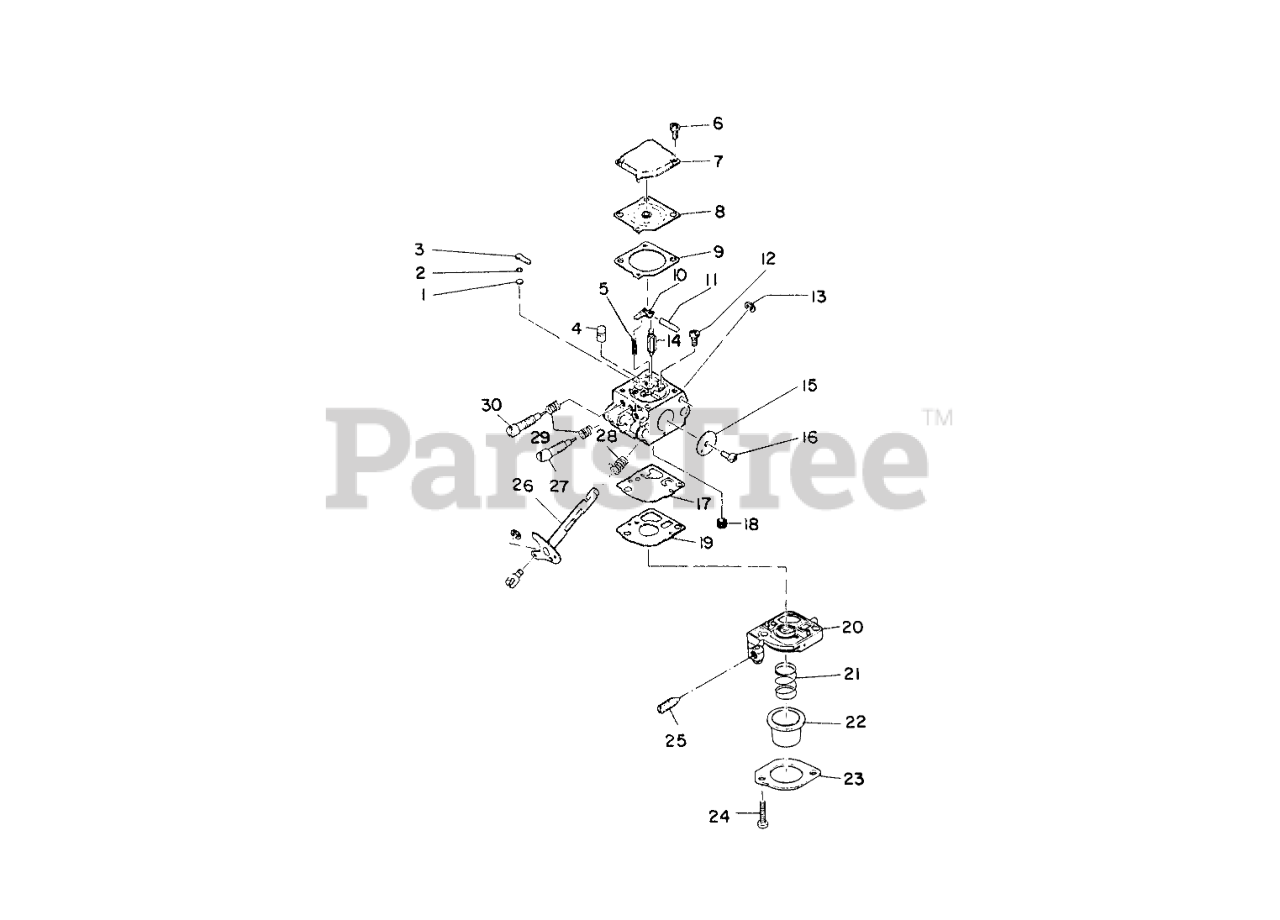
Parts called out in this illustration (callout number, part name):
1	Valve Check
2	Retainer-Check Valve
3	Plug-Welch
4	Nozzle Ass-y-Check Valve
5	Spring
6	Screw
7	Cover
8	Diaphram-Metering
9	Gasket
10	Lever-Metering
11	Pin-Metering
12	Screw
13	Ring-E
14	Valve-Inlet Needle
15	Valve-Throttle
16	Screw
17	Diaphram-Pump
18	Strainer
19	Gasket
20	Base Assembly-Primer (Incl. Ref. #25)
21	Spring
22	PRIMER
23	Retainer-Primer
24	Screw
25	Screw-Idle Adjustment
26	Shaft Throttle Assembly
27	Screw-Low Speed Adj.
28	Spring-Throttle
29	Spring
30	Screw-High Speed Adj.
